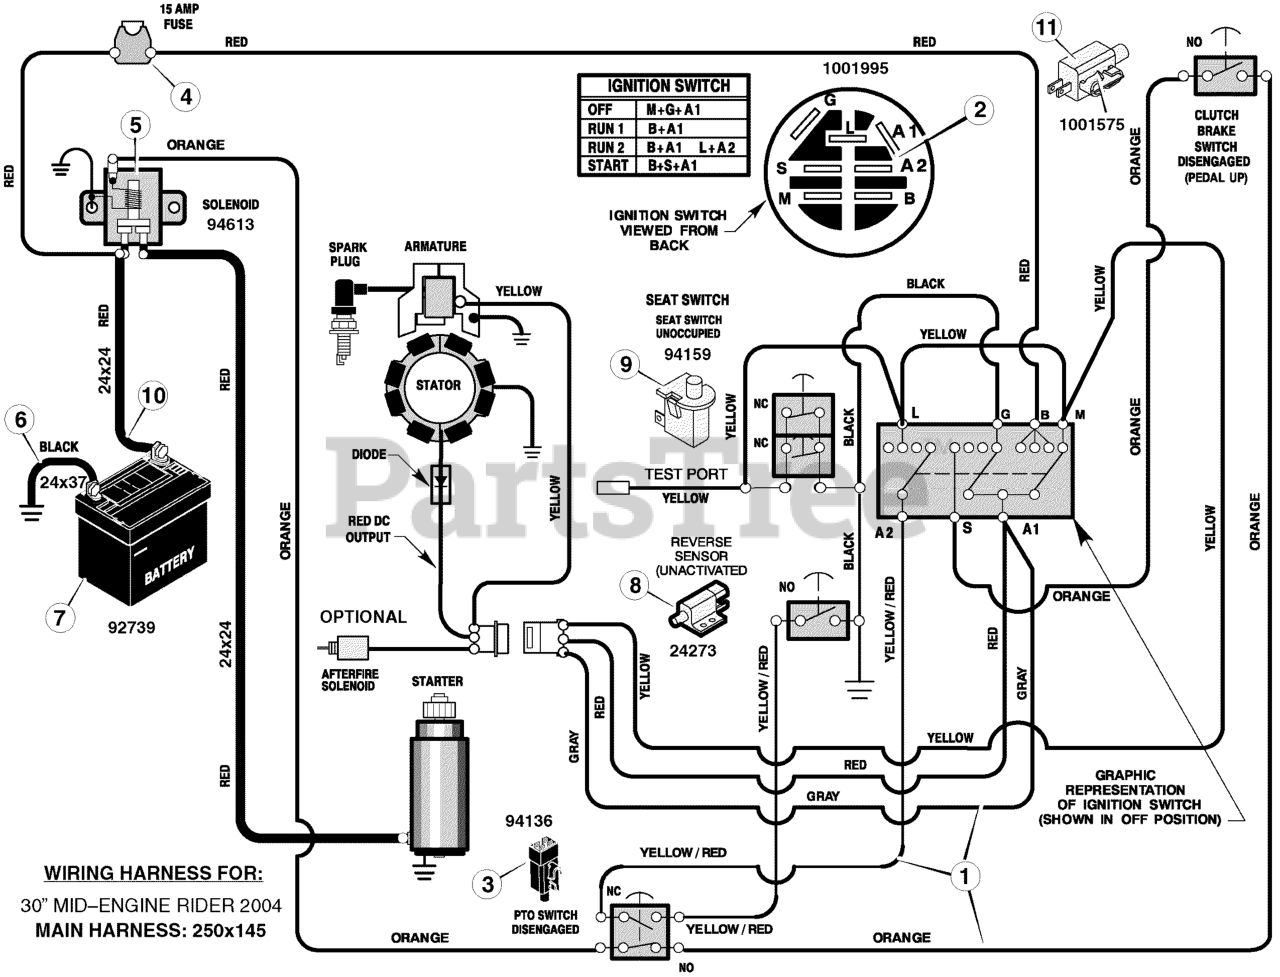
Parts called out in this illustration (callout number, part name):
1	Harness, Chassis Wire
2	Switch, Ignition
2	Key, Ignition
3	Switch, Limit (PTO)
4	Fuse
4	Holder, Fuse
5	Solenoid
5	Screw, Mounting
5	Locknut
6	Cable, Battery Ground
6	Screw, Ground Cable
7	Battery
7	BOOT, Battery Terminal, Positive
7	Bolt, Carriage
7	Wingnut
8	Switch, Select Reverse
8	Screw, Mounting
9	Switch, Seat Sensor
10	Cable
11	Switch, Clutch Brake
